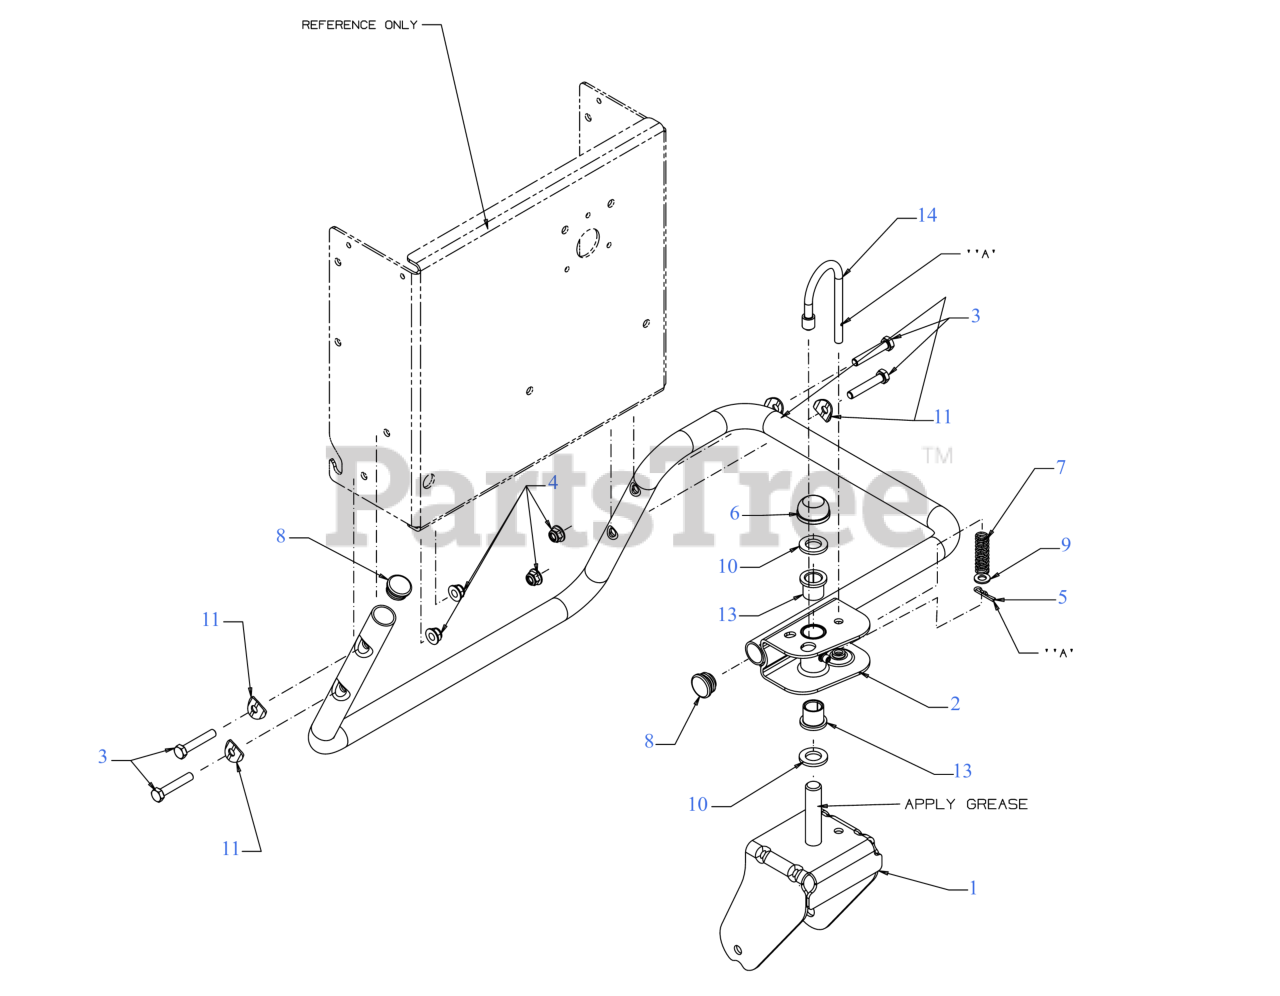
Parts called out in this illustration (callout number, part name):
3	SCREW 5/16-18 x 1.75 GR5
4	FLANGE LOCK NUT 5/16-18
5	COTTER PIN .072 DIA. 1.13 LG
7	COMPRESSION SPRING .531 OD 1.75 LG
9	FLAT WASHER .344 x .62
10	FLAT WASHER
11	SADDLE WASHER
13	BEARING:FLANGE .631 ID
